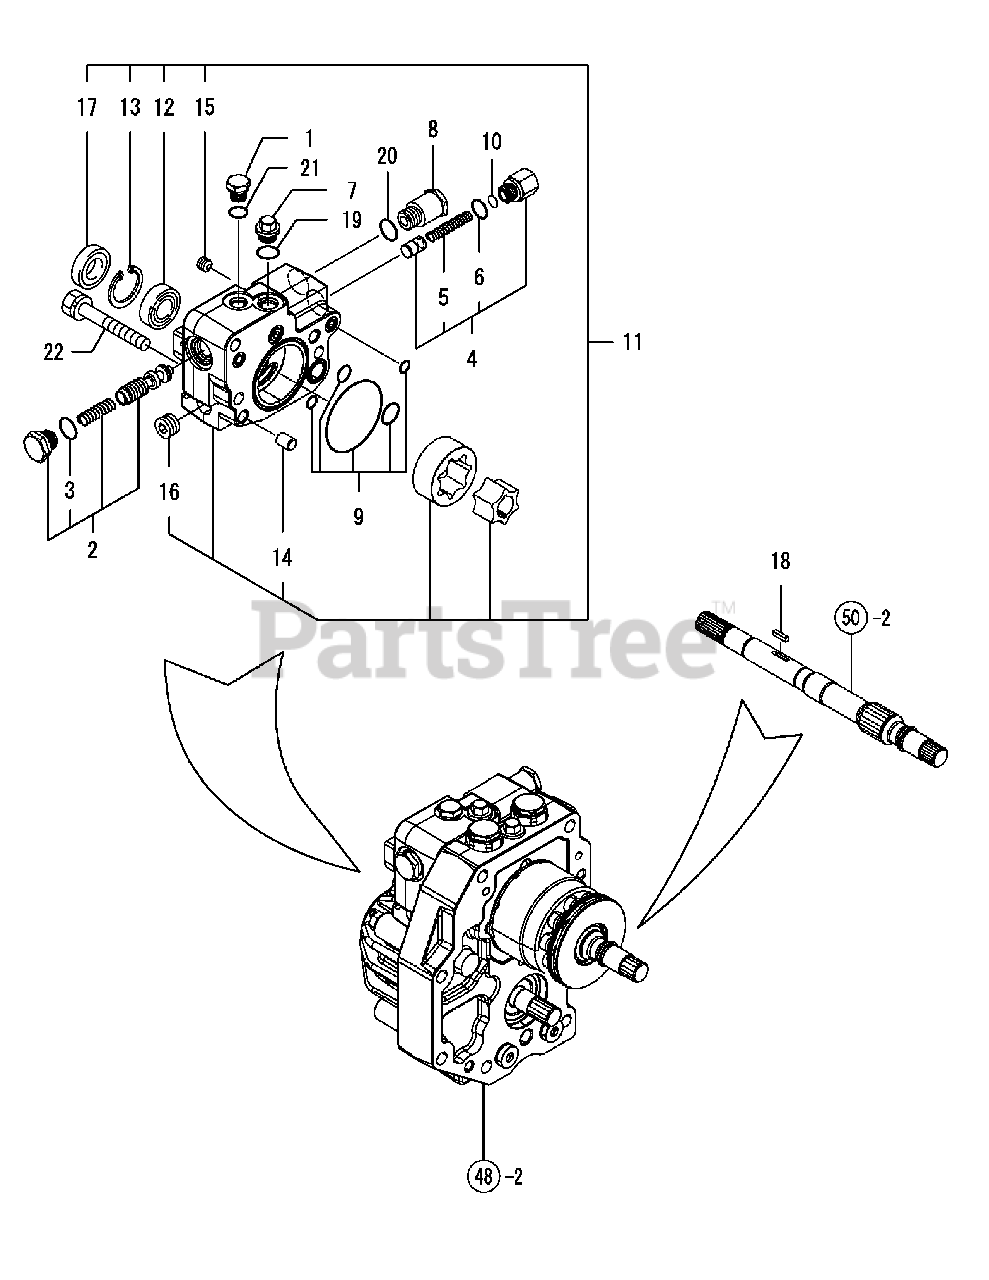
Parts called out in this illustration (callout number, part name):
1	Plug 1/2-20 Unf
2	Reducing Valve Comp.
3	O-Ring 1A P-14.0
4	Pressure Valve Comp.
6	O-Ring 1A P-12.0
11	Body Assy, Pump
14	Parallel Pin, M10X12
15	Plug Pt1/8,Screw
16	Plug Pt3/8,Screw
17	Seal Tc22 35 08, Oil
19	O-Ring 1A P-12.0
20	O-Ring 1A P-14.0
21	Packing 1A As 905
